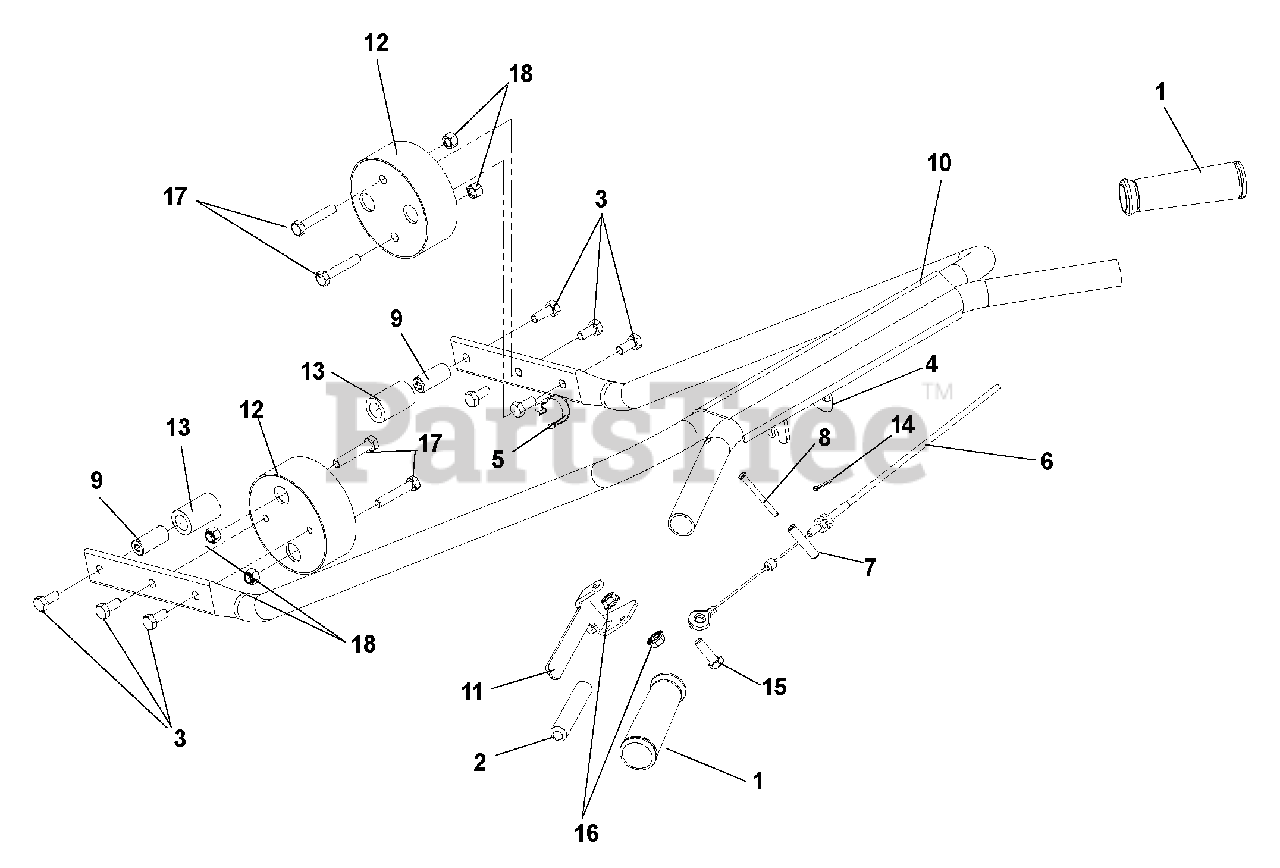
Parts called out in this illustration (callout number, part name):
1	GRIP, HANDLE
2	GRIP, VINYL
3	HCS, M8-1.25 X 22MM, GR8.8
4	TUBE CLAMP, DOUBLE
5	CLIP, CABLE
6	CABLE PULL
7	ROLL PIN, 5/16 X 1 1/2
8	PIN, CLEVIS
11	LEVER, THROTTLE
12	HANDLE ATTACHMENT HARDWARE
14	PIN COTTER, 3/32 X 3/4
15	HCS, 5/16-18 X 1, GR5
16	NUT, 5/16-18, WHIZLK
17	HCS, 5/16-18 X 1 3/4, GR5
18	NUT, 5/16-18, NYLOC
